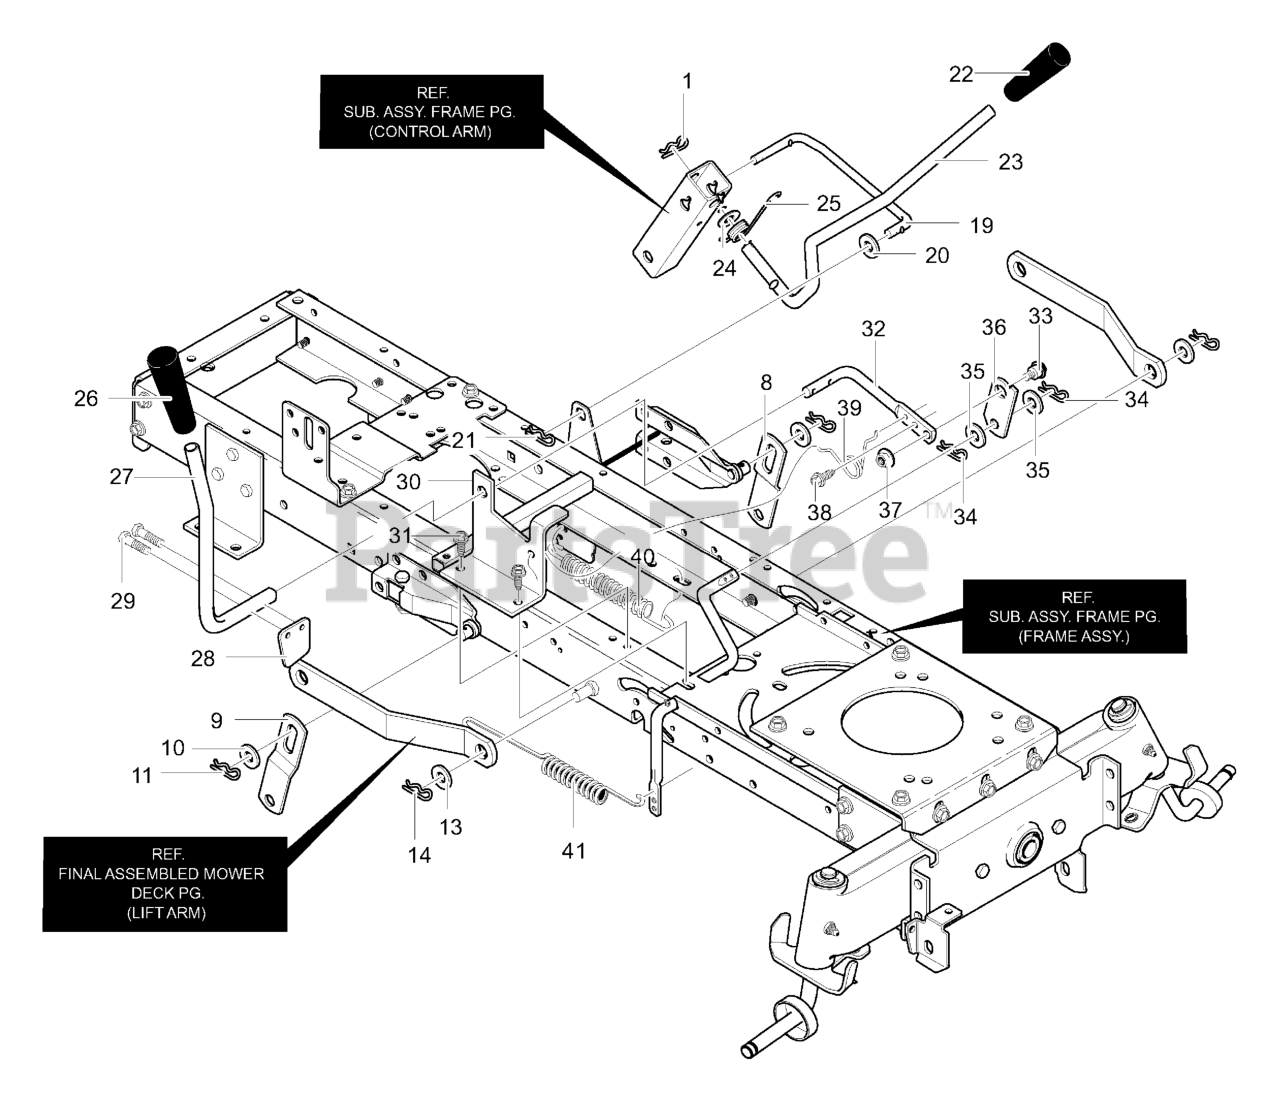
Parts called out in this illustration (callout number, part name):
1	Hair Pin
8	Link, Lift LH
9	Link, Lift RH
10	Flat washer
11	Hair Pin
13	Flat washer
14	Hair Pin
19	Link, Lift Handle
20	Flat washer
21	Hair Pin
22	Grip
23	Handle, Lift
24	Washer, Flat
25	Torsion Spring
26	Grip, PTO
27	PTO Handle
28	Paddle Switch
29	Screw, Thd Form
30	Bracket, PTO
31	Screw, 5/16-18 x 0.50
32	Lever, PTO
33	Bolt, Shoulder 3/8-16
34	Hair Pin
35	Washer, Flat
36	Link PTO
37	Nut, 3/8-16
38	Screw, 5/16-18 x 0.75
39	Torsion Spring
41	Spring, Extension
